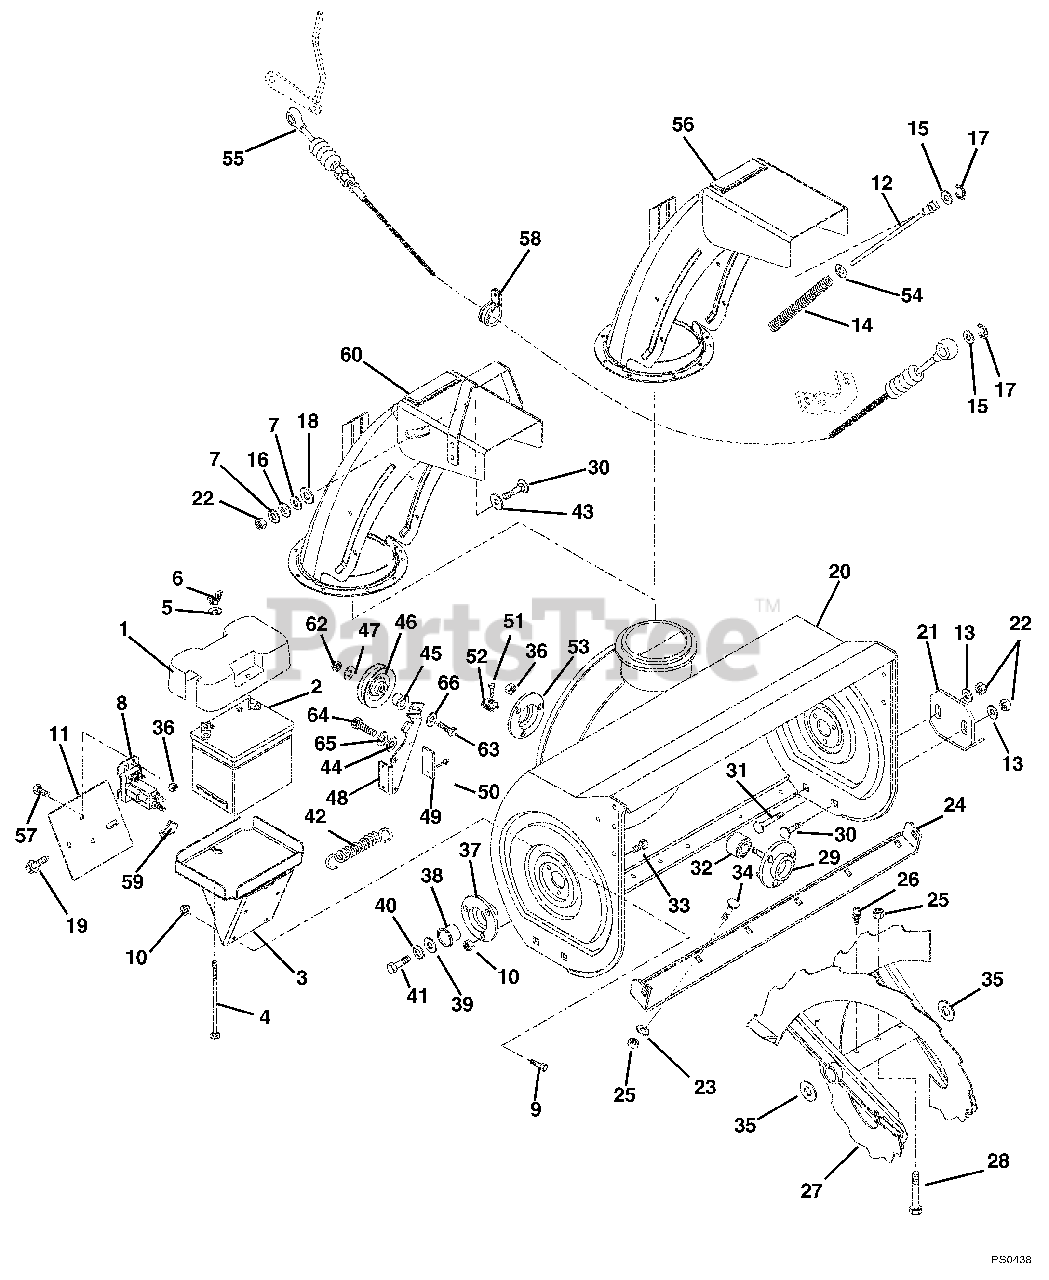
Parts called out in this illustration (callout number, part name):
1	COVER, BATTERY
3	TRAY, BATTERY - (36")
3	TRAY, BATTERY
4	@BLT-RDHDSQNK .25-20X7.00 G2YZ
5	@WSHR-FL-STL.281X.62X.065 YWZC
6	NUT-LK WING .250-20 YWZC
7	@WSHR-FL-STL.406X.812X.065 YWZ
8	SOLENOID
9	@BLT-HEX .25-20X.75 GR5 YWZC
10	@NUT-SPNLK-FLG .25-20 YWZC
11	COVER, SOLENOID
12	ROD, CHUTE
13	@WSHR-FL-STL.438X1.00X.083 YWZ
14	SPRING, COMP. .08 X .40 X 7.15
15	@WSHR-FL-STL.281X.62X.065 YWZC
16	WAVE WASHER .390X.655X.110
17	RG-RTNG-EXT .218X.035 TYPE E
18	WSHR-PLASTIC .390X.875X.062
19	@SCR-TAP .25-20X.50 HWH TR YWZ
20	HOUSING, BLOWER-28"(STAG)
20	HOUSING, BLOWER-24"(HIGH)
20	HOUSING, BLOWER-24"(HIGH/12V)
20	HOUSING, BLOWER-28"(HIGH/12V)
20	HOUSING, BLOWER-32"(HIGH/12V)
20	HOUSING, BLOWER-36"
20	HOUSING, BLOWER-24"(STAG)
21	RUNNER, SKID SHOE-1/2" FLANGE
21	SKID SHOE, REVERSIBLE - ORANGE
22	@NUT-LK-CTR .38-16 YWZC
23	@WSHR-FL-STL.38X.875X.083 YWZC
24	SCRAPER, BLADE 28"
24	SCRAPER, BLADE 24"
24	BLADE, SCRAPPER - 28"
24	BLADE, 32" SCRAPPER
24	BLADE, SCRAPPER - 36"
25	@NUT-LK-CTR .31-18 YWZC
26	FTG-LUBE .25-28X.256 YWZC
27	RAKE, LEFT-28"(1"ID X 15.75OD)
27	RAKE, RIGHT-28"(1ID X 15.75OD)
27	RAKE, R.H.-24"(1 ID X 15.75OD)
27	RAKE, L.H.-24"(1 ID X 15.75OD)
27	RAKE, LEFT-28"(1"ID X 14.75OD)
27	RAKE, RIGHT-28"(1ID X 14.75OD)
27	RAKE, LEFT-32"(1"ID X 15.75OD)
27	RAKE, RIGHT-32"(1ID X 15.75OD)
27	RAKE, LEFT-36"(1"ID X 15.75OD)
27	RAKE, RIGHT-36"(1ID X 15.75OD)
27	RAKE, LEFT-24"(1"ID X 14.75OD)
27	RAKE, RIGHT-24"(1ID X 14.75OD)
28	SHEAR BOLT SERVICE ASSEMBLY
29	BEARING FLANGE
30	BLT-RHHDSQSHNK .38-16X.75 G2YZ
31	@BLT-RDHDSHSQNK.38-16X1.0 G5YZ
32	BRG-BALL1.0X2.0X.56
32	BRG-BALL .750X1.750X.50
33	BLT-SERNK SL .25-20X.50 YWZC
34	@BLT-RHDSSQNK .31-18X.62 G5YZ
35	WSHR-FL-STL 1.010X1.505X.062YZ
36	@NUT-LK-CTR .25-20 YWZC
37	BEARING SUPPORT
38	BSHG-FLG 1.000X1.12X.62X1.50BR
39	WSHR-FL-STL.511X1.441X.125 YWZ
40	WSHR-LK .500X.151 HVY YWZC
41	@BLT-HEX .50-13X1.00 GR5 YWZC
42	SG-TENS .080X.687X5.16 WLD 28
43	WSHR-FL-STL .52X.827X.062 YWZC
44	WSHR-FL-STL .328X1.0X.094 YWZC
45	SPCR, BRG .315X.50X.688X.281
46	IDLER
47	@WSHR-FL-STL.344X.688X.065YWZC
48	ARM, AUGER/BRAKE-HIGH W/LINING
48	ARM, BRAKE/AUGER-STAG W/LINING
49	BRAKE LINING
50	RVT-TBLR .187X.437 RH ST PL
51	BLT-SERHFWH .38-16X.75 YWZC
52	NUT-RETNR .38-16 TINRMAN
53	BEARING FLANGE
54	@WSHR-FL-STL.344X.688X.065YWZC
55	CABLE, DEFLECTOR CONTROL
56	CHUTE, DISCHARGE - W/REMOTE
56	CHUTE, DISCHARGE - ELECTRIC
57	@BLT-HEX .25-20X.50 GR5 YWZC
58	CLAMP, CUSHIONED STEEL
59	BOOT, EYELET TERMINAL
60	CHUTE, DISCHARGE - MANUAL
61	@WSHR-LK .25X.062 REG YWZC
62	@NUT-LK-CTR .31-18 YWZC
63	@BLT-HEX .31-18X1.25 GR5 YWZC
64	@BLT-HEX .31-18X.75 GR5 YWZC
65	WSHR-LK .312X.097 HVY YWZC
66	@WSHR-FL-STL.38X.875X.083 YWZC
